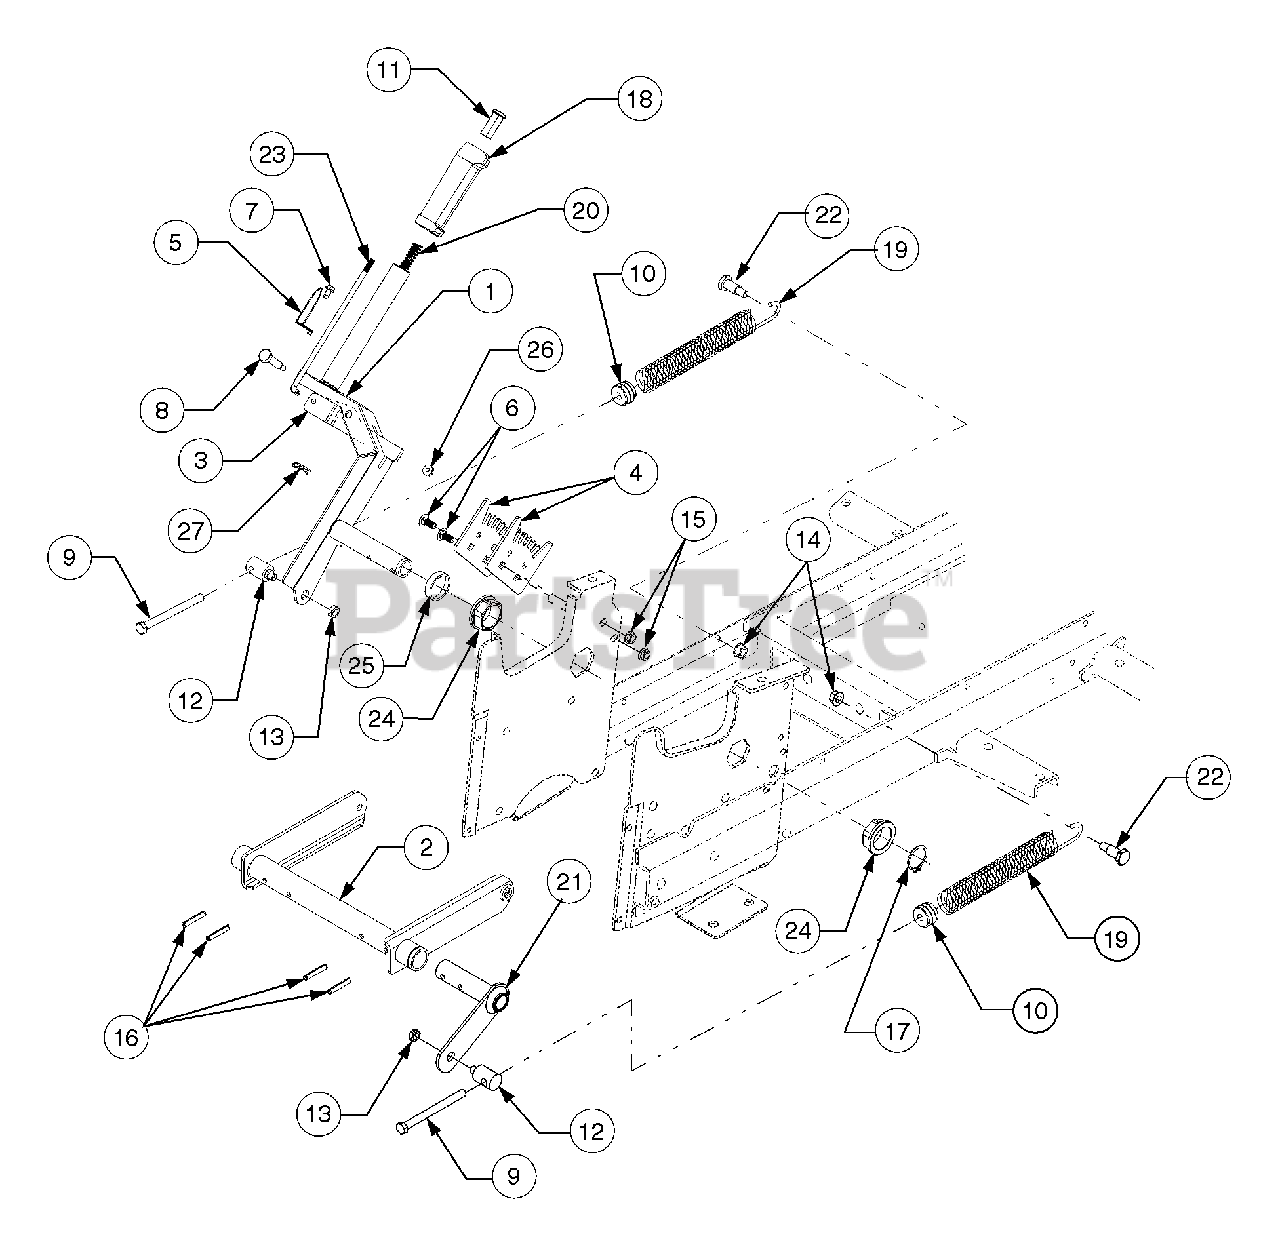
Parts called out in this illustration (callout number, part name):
2	Shaft Assembly, Lift
5	Indicator, Lift Height
6	Bolt, Carriage, 5/16-18 x .75
7	Screw, Hex Wash Tapp, 1/4 x .5
8	Screw, Shoulder, .374 x 1.375
9	Screw, Hex Cap, 3/8-16 x 4.25 GR5
10	Insert, Spring
11	Button, Handle
12	Ferrule, Adjustment
13	Nut, Hex Center Lock, Jam, 3/8-24
14	Nut, Hex Flanged Lock, 3/8-16
15	Nut, Hex Flanged Top Lock, 5/16-18
16	Pin, Spiral Spring, 1/4 Dia x 1.5
17	Ring, Snap, 1.25 Dia Shaft
18	Grip, Lift Handle
19	Spring, Extension
20	Spring, Compression
22	Bolt, Shoulder
23	Rod, Index
24	Bearing, Hex Flange, 1.25 ID
25	Spacer, 1.28 ID x 1.5 OD x .335 Lg
26	Nut, Hex Flange Lock, 1/4-20
27	Pin, Internal Cotter
